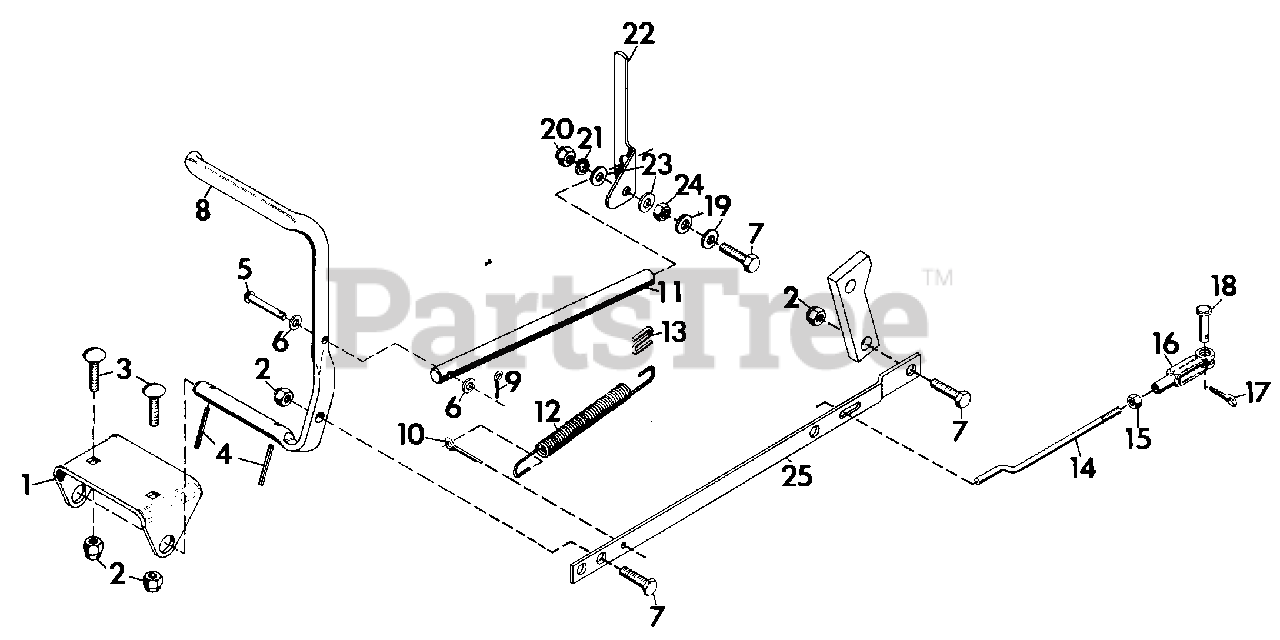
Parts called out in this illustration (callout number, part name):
1	BRACKET, BRAKE PEDAL
2	NUT, LOCK 3/8-16
3	BOLT, CARRIAGE 3/8-16X.75
4	PIN, SPRING .187X1.25
5	PIN, CLEVIS .25X1.50
6	WASHER, FLAT .281X.625X.065
7	BOLT, HEX 3/8-16X1.25
8	PEDAL, BRAKE
9	PIN, COTTER .06X.75
10	PIN, COTTER .25X1.00
11	ROD
12	SPRING, EXT. 5.50X.50X20 RATE
13	CLIP, SPRING
14	LINK, REAR
15	NUT, HEX 1/4-28
16	CLEVIS, ADJUSTABLE 1/4-28
17	PIN, COTTER .078X.627
18	PIN, CLEVIS .25X.766
19	WASHER, FLAT .406X.812X.065
20	NUT, LOCK 3/8-16
21	WASHER, LOCK 3/8
22	ARM, PARKING BRAKE LOCK
23	WASHER, NYLON .375X.75X.06
24	NUT, JAM 3/8-16 HEX
25	LINK, FRONT
